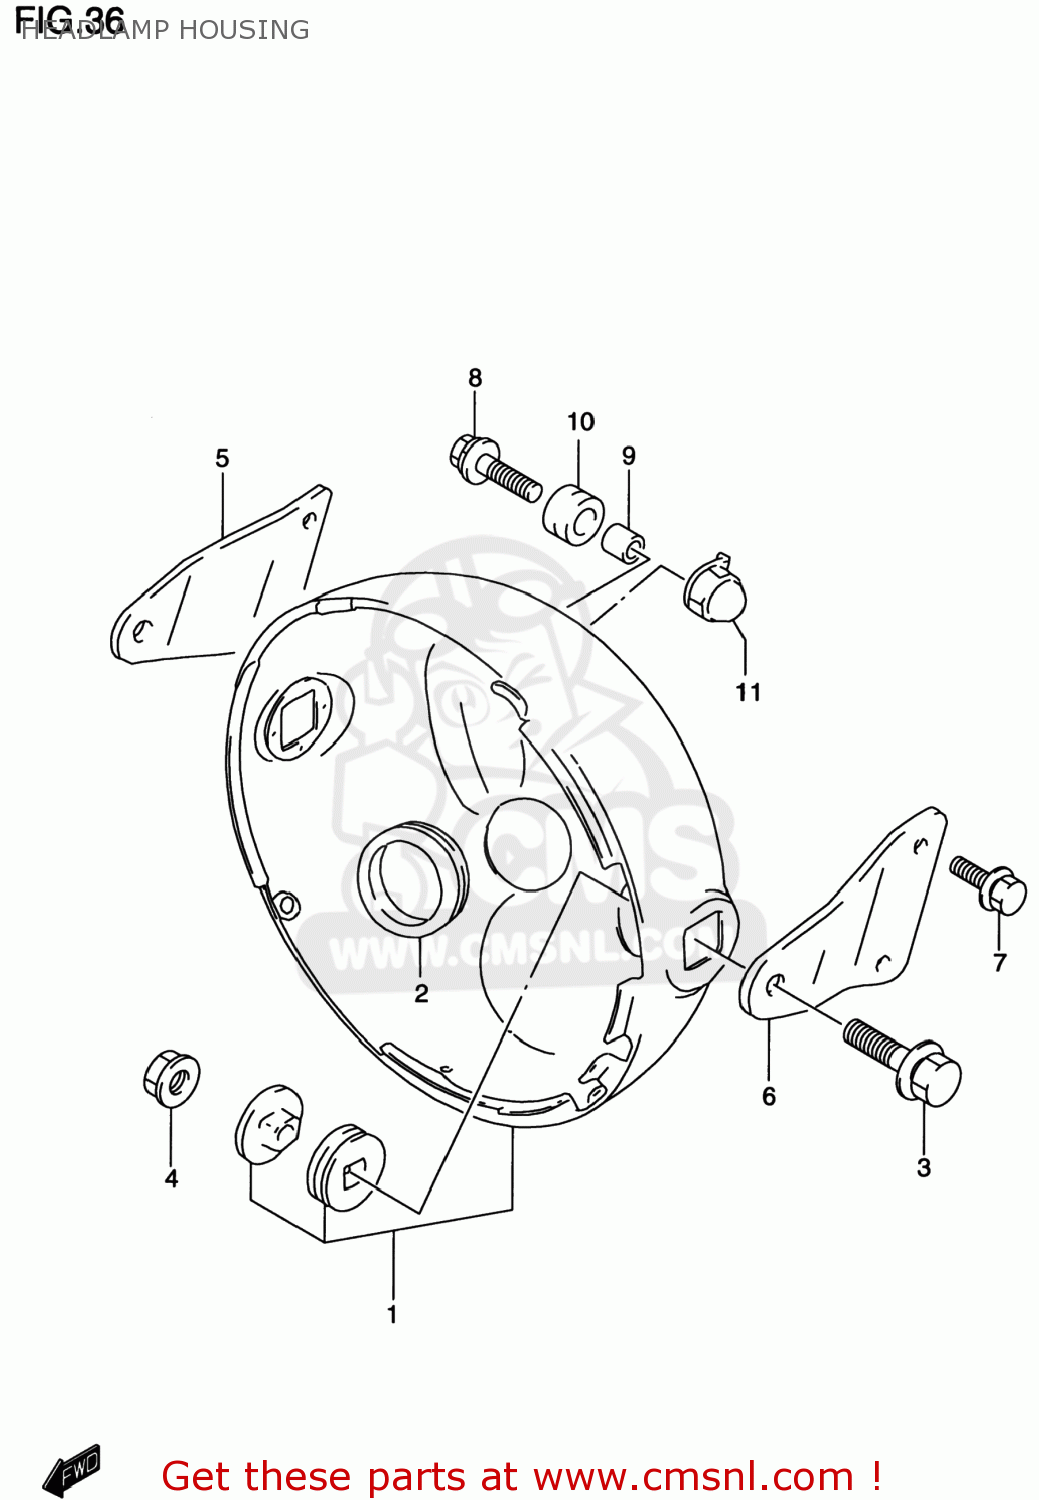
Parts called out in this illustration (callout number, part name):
1	HOUSING,HEADLAMP
2	GROMMET
3	BOLT
4	NUT
5	STAY,HEADLAMP HOUSING,R
6	STAY,HEADLAMP HOUSING,L
7	BOLT
8	BOLT
9	SPACER(6.5X10.5X12)
10	CUSHION
11	PLATE,HEADLAMP
